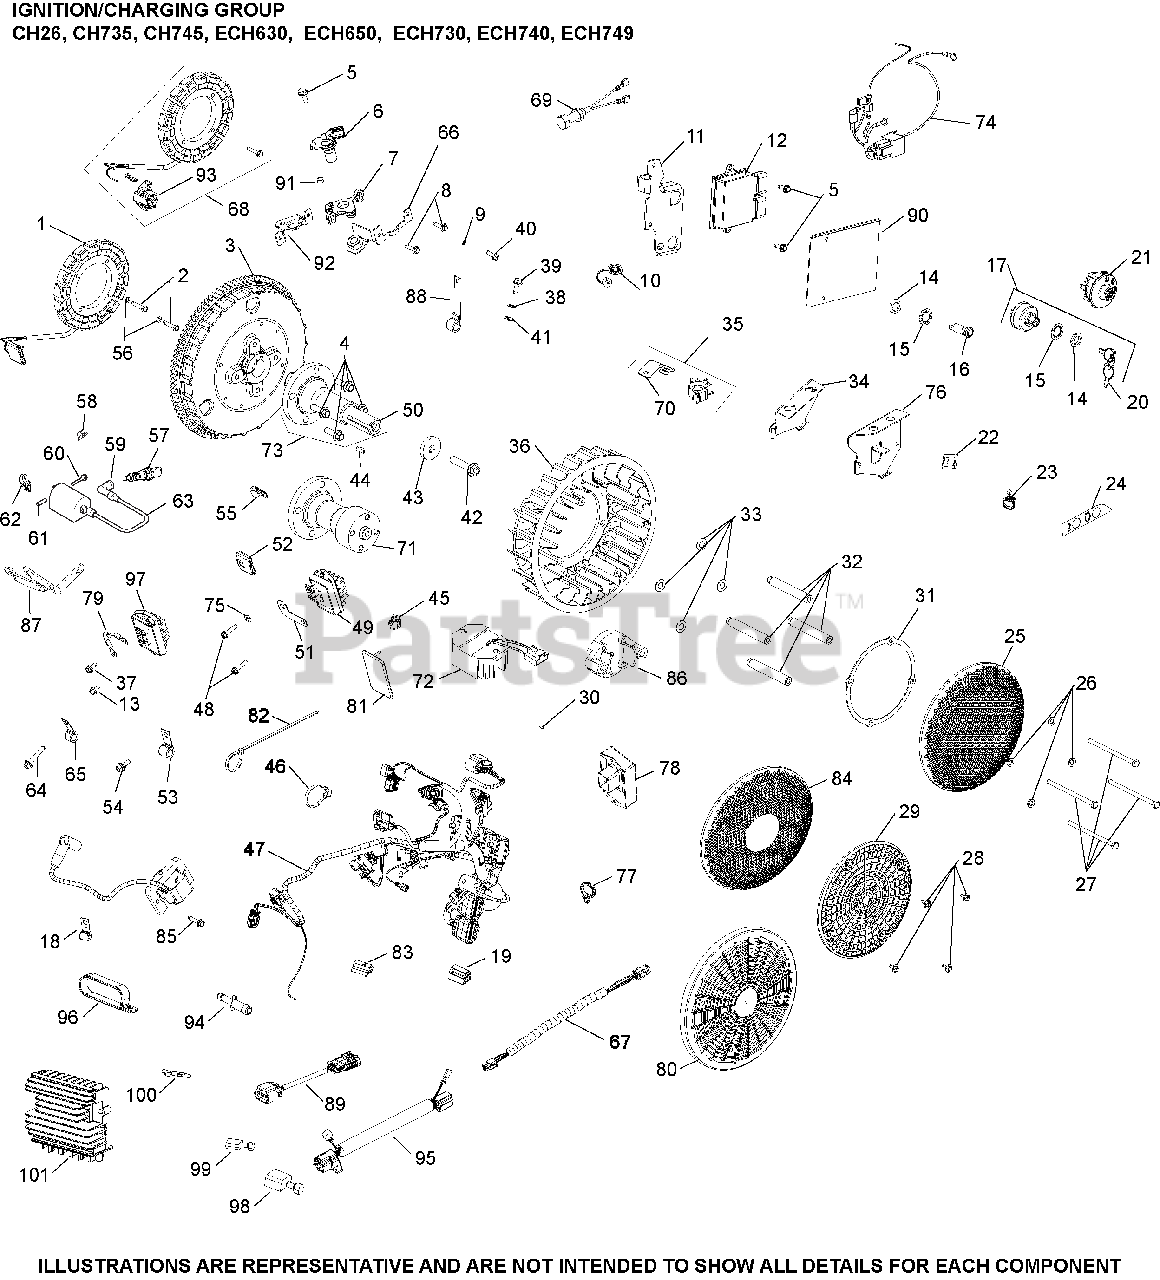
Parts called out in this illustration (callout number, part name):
1	KIT, 15 / 20 AMP STATOR
2	SCREW, THREAD FORMING
3	FLYWHEEL ASSEMBLY (LW)
5	SCREW, THREAD FORMING
6	SENSOR, SPEED
7	BRACKET, SENSOR SPEED
8	SCREW, THREAD FORMING
9	WASHER, INT TOOTH LOCK #10
10	CAP, CONNECTOR
11	BRACKET, ECU
12	MODULE, ECU
26	WASHER, FLAT 1/4" (O.D. 5/8")
28	SCREW, CAP M6X1.0X99.5
29	SCREEN, GRASS
30	SCREW, FLG M10X1.5X45 - (#25086361S)
31	RING, SUPPORT
33	WASHER, SPRING 10 MM
35	KIT, MOUNTING CLIP
36	FAN USE 24 755 253-S
37	SCREW, THREAD FORMING
38	WASHER, INT TOOTH LOCK 1/4"
41	WASHER, FLAT 1/4" (O.D. 1/2")
42	SCREW, SKT SET #10-24X1/4"
43	WASHER, FLAT 13/32"
44	KEY, 3/16" X 5/8"
47	HARNESS, WIRING ASSEMBLY
48	SCREW, HEX FLANGE HI-LO
52	CONNECTOR
57	PLUG, SPARK (STD)
62	CLIP, SNAP-IN
63	COIL, IGNITION - EFI
64	SCREW, FLG M6X1.0X34
70	CLIP, MOUNTING BRACKET USE 25 154 21-S
96	CLAMP, INSULATED DOUBLE
97	REGULATOR, RECTIFIER (20-30AMP,FW W/O USE 25 403 39-S
